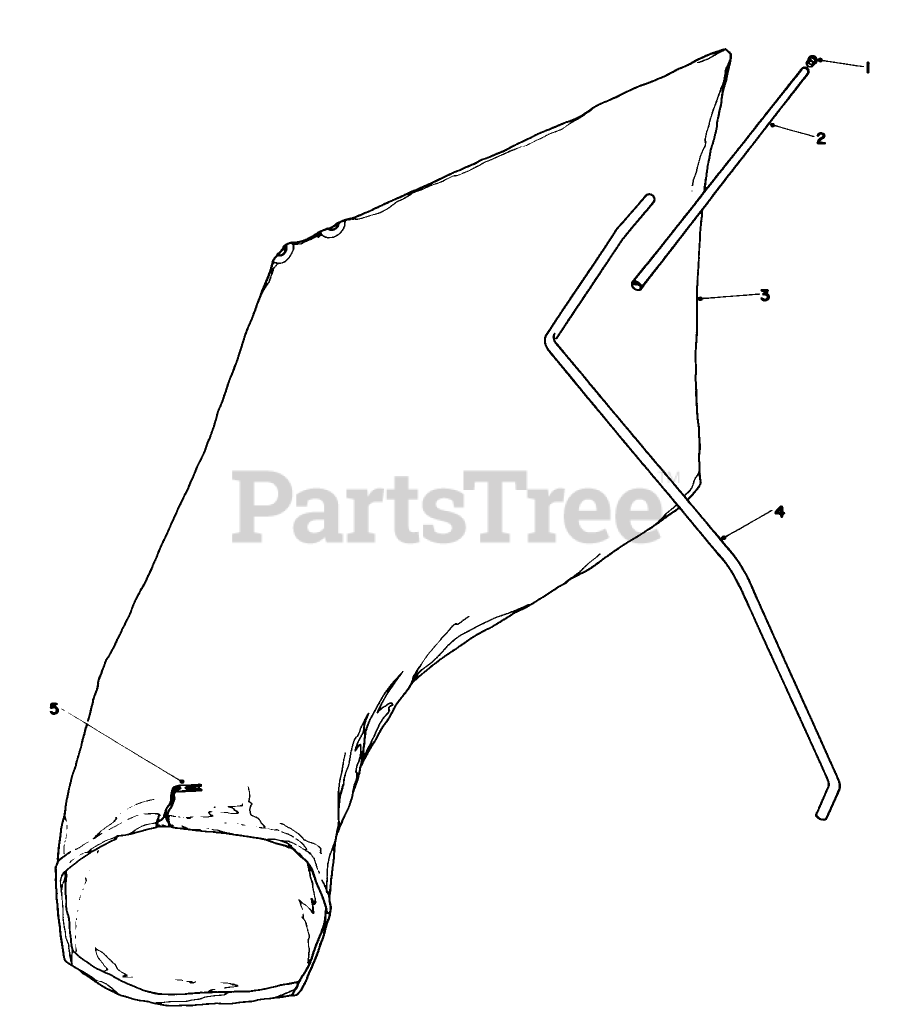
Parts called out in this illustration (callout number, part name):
2	BAG HANGER TUBE
4	HANGER ROD
5	BAG CORD FASTENER
